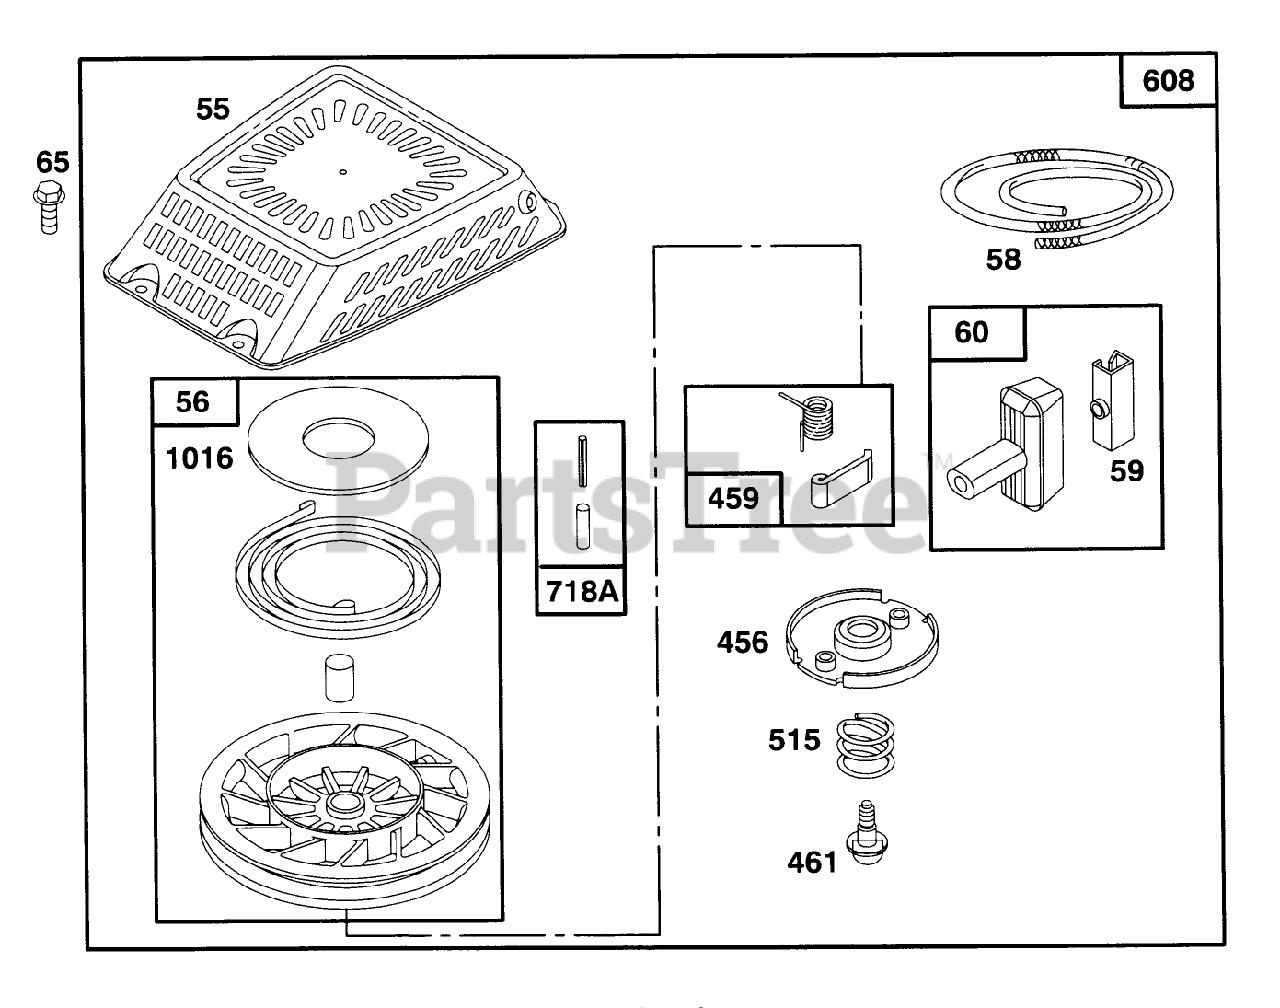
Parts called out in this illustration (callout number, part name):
59	INSERT-HANDLE, REWIND
456	RETAINER - SPRING
515	SPRING - RETAINER
